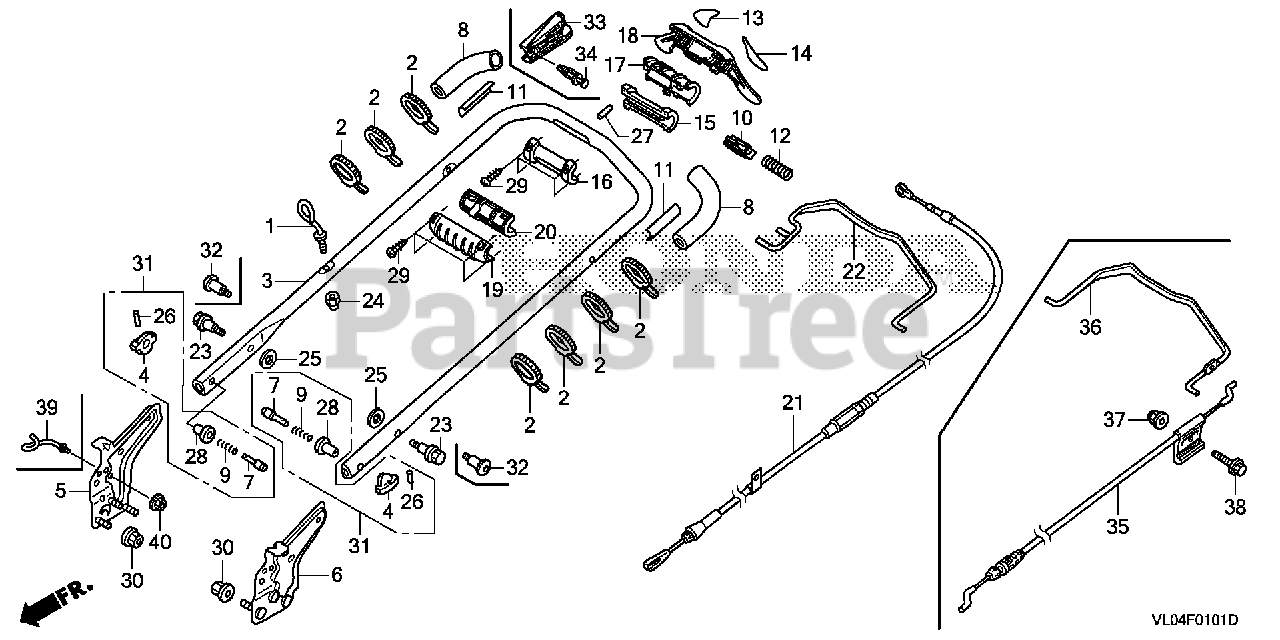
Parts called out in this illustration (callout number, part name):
1	GUIDE, ROPE
2	TIE, CABLE (157.5MM)
3	PIPE, HANDLE *NH105* (MAT BLACK)
4	GRIP, HANDLE JOINT *NH164* (GRIP GRAY)
5	STAY, R. HANDLE
6	STAY, L. HANDLE
7	PIN (8MM)
8	GRIP, HANDLE
9	SPRING, HANDLE ADJUSTING
10	LEVER, SELECT
11	HOLD, GRIP
12	SPRING, SELECT LEVER
13	GRIP, R. PAD
14	GRIP, L. PAD
15	BRACKET, GRIP (UPPER)
16	BRACKET, GRIP (LOWER)
17	COVER, BRACKET (UPPER)
18	GRIP, CLUTCH (UPPER)
19	GRIP, CLUTCH (LOWER)
20	COVER, BRACKET (LOWER)
21	CABLE, CLUTCH
22	LEVER, ROTO-STOP *NH105* (MAT BLACK)
24	NUT, NYLON LOCK (6MM)
25	WASHER (25MM)
26	PIN, COILED (2X12)
27	ROLLER (5X37)
28	COLLAR, HANDLE HEIGHT ADJUSTING
29	SCREW, TAPPING (4X12)
30	NUT, FLANGE (8MM)
32	BOLT, SPECIAL (8X32)
